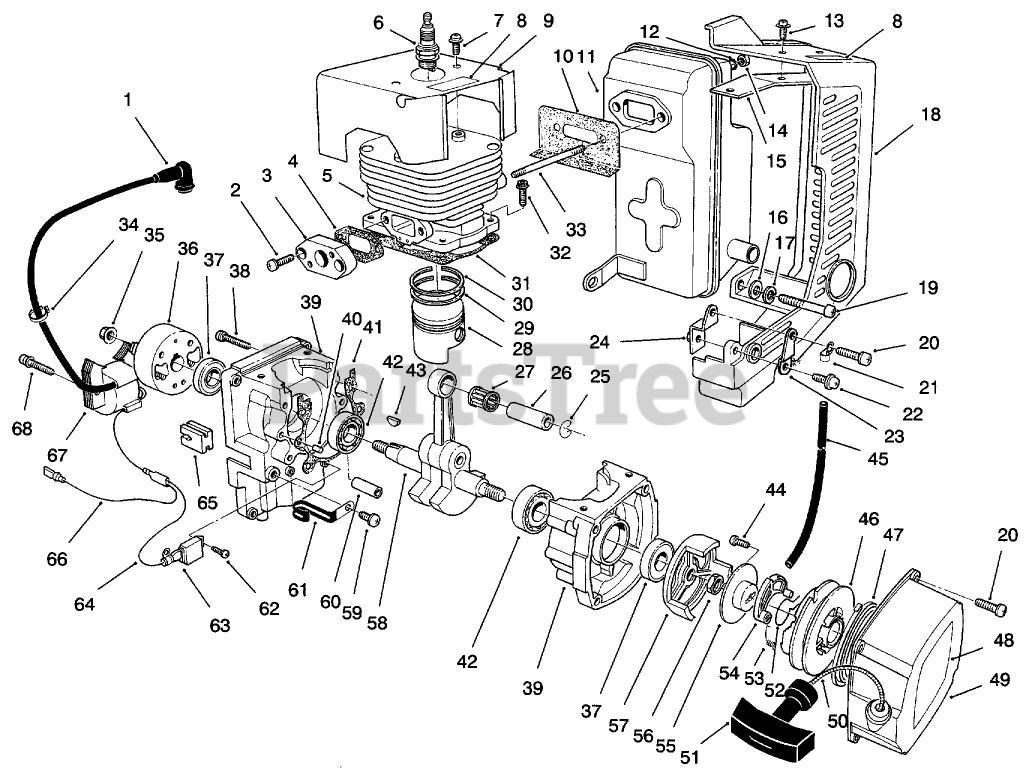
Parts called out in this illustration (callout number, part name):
1	CAP-PLUG
2	SCREW & WASHER
3	FLANGE
4	GASKET
5	CYLINDER
6	SPARK PLUG
7	SCREW & WASHER
8	DECAL-SURFACE, HOT
9	CYL COVER
10	MUFFLER GASKET
11	MUFFLER
13	SCREW & WASHER
15	BRACKET
18	MUFFLER COVER
20	SCREW & WASHER
27	NEEDLE BEARING
28	PISTON SET
31	GASKET
33	STUD BOLT
36	ROTOR
37	OIL SEAL
38	SCREW & WASHER
39	CRANKCASE
41	GASKET
44	SCREW
45	FUEL TUBE
49	STARTER CASE
51	STARTER KNOB
53	SPRING, RETURN
56	J/S NUT
57	STARTER PULLEY
64	LEAD WIRE
68	BOLT AND WASHER
